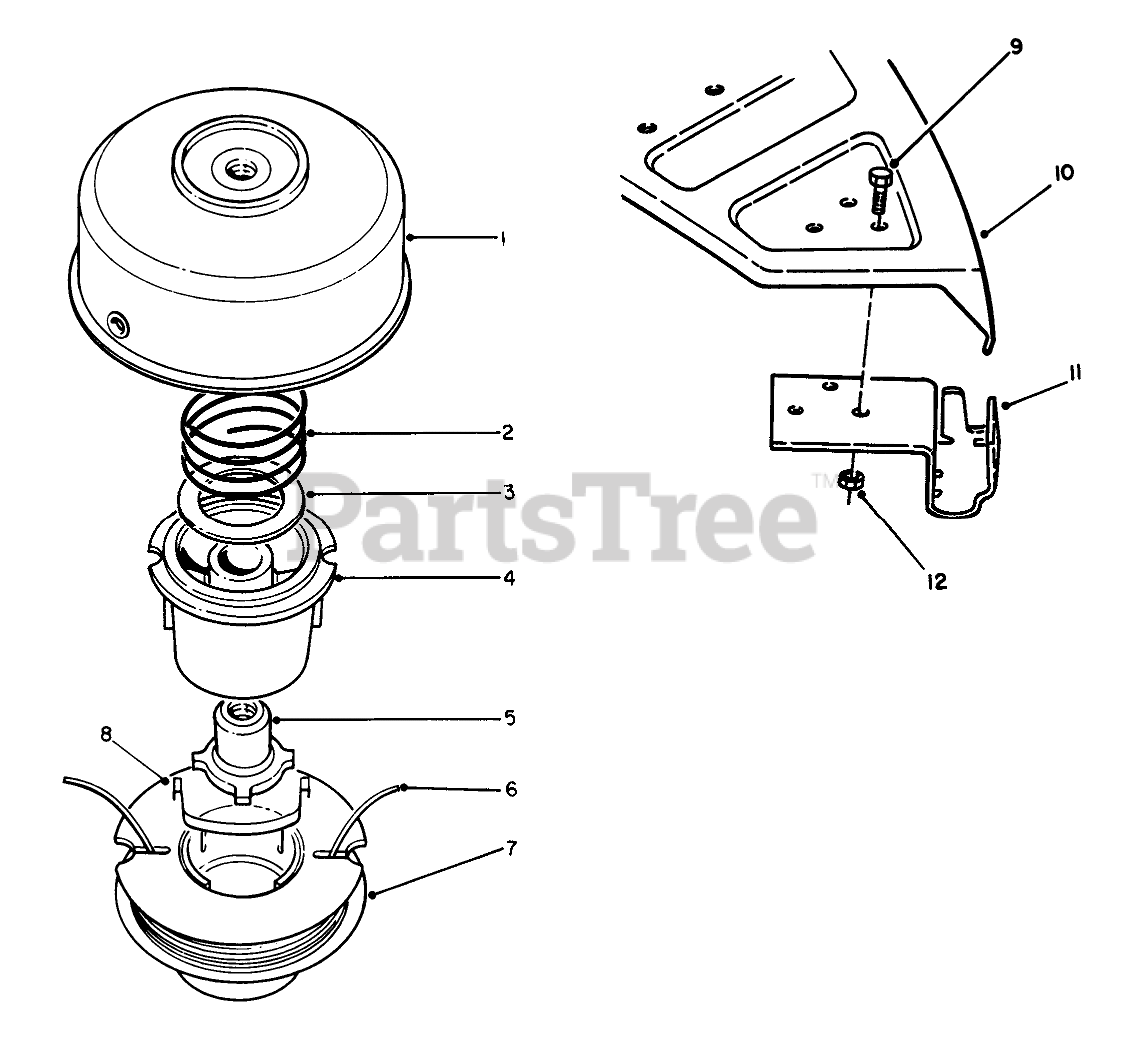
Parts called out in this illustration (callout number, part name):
1	ASM - TRIMMER DRUM & EYELET
2	SPRING
3	WASHER-FLAT
4	SPOOL CORE
5	LH DRIVER
6	REPL LINE PKG
7	Prewound Spool (Incl. Ref. #8)
8	SADDLE-SPOOL CAP
9	SCREW-SHH
10	Shield-Grass
11	BRACKET & KNIFE ASM
12	NUT-LOCK, NI
